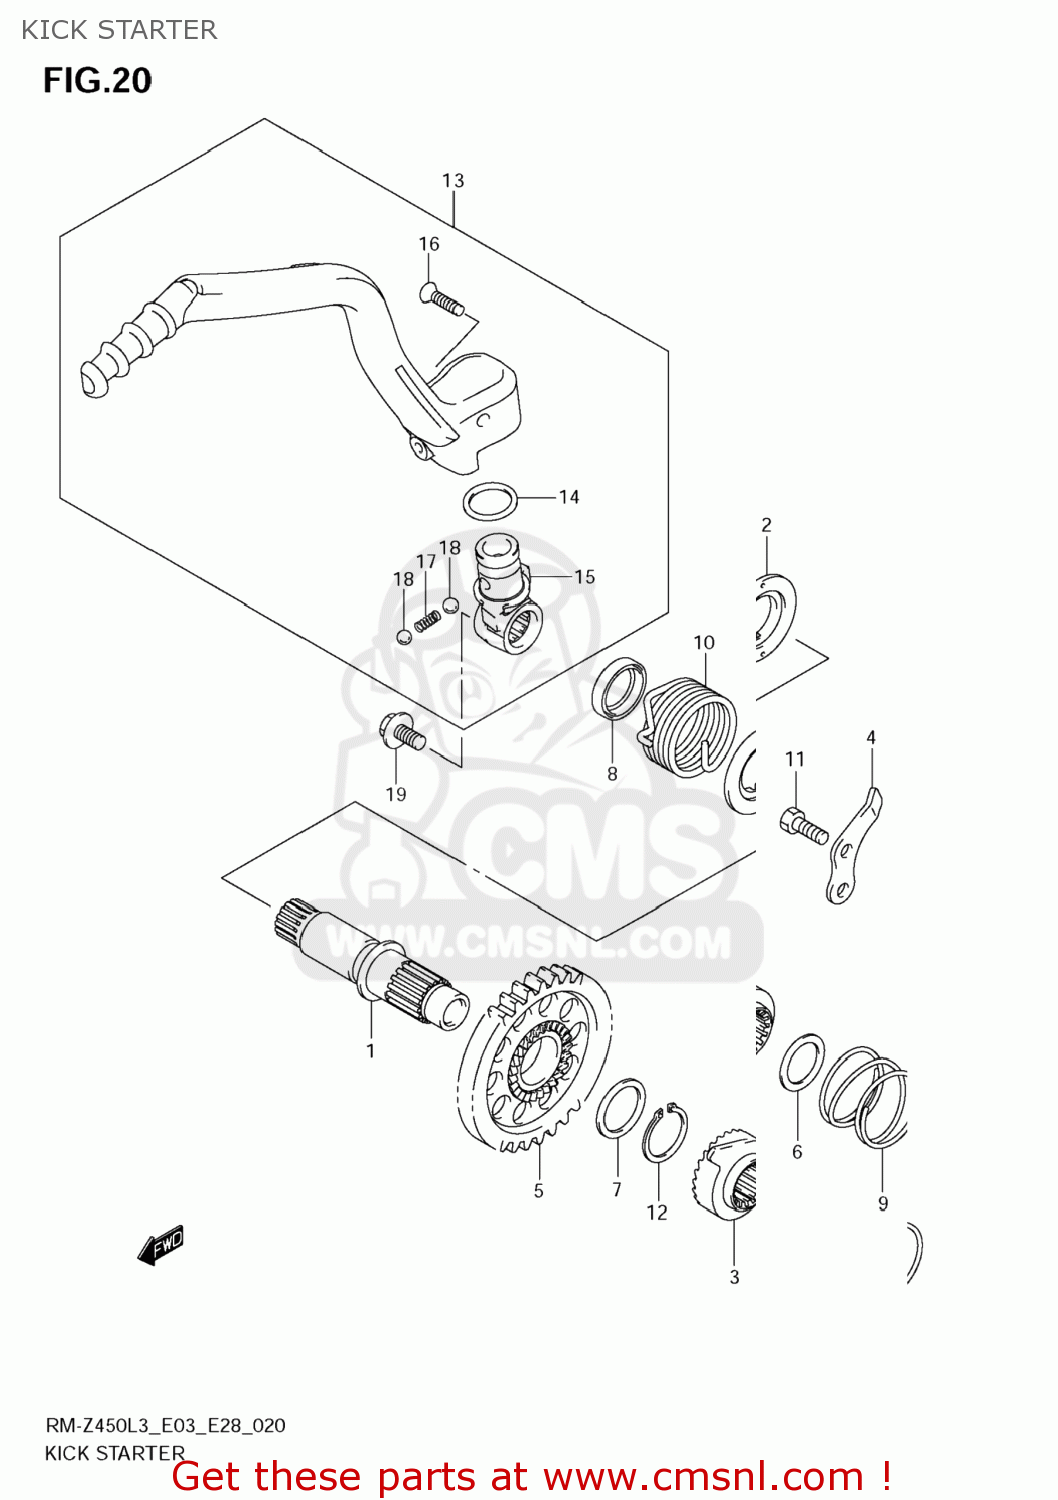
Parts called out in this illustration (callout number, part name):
1	SHAFT,KICK STARTER
2	GUIDE,KICK STARTER SFT SPRING
3	STARTER,KICK
4	GUIDE,KICK STARTER
5	GEAR,KICK STARTER DRIIVE
6	SHIM(17X24X0.5)
7	SHIM(20X26X1)
8	SEAL,OIL(20X27X5)
9	SPRING
10	SPRING
11	BOLT
12	CIRCLIP
13	LEVER ASSY,KICK STARTER
14	O RING,KICK STARTER
15	JOINT,KICK STARTER LEVER
16	SCREW(6X27.5)
17	SPRING
18	BALL
19	BOLT(8X14)
